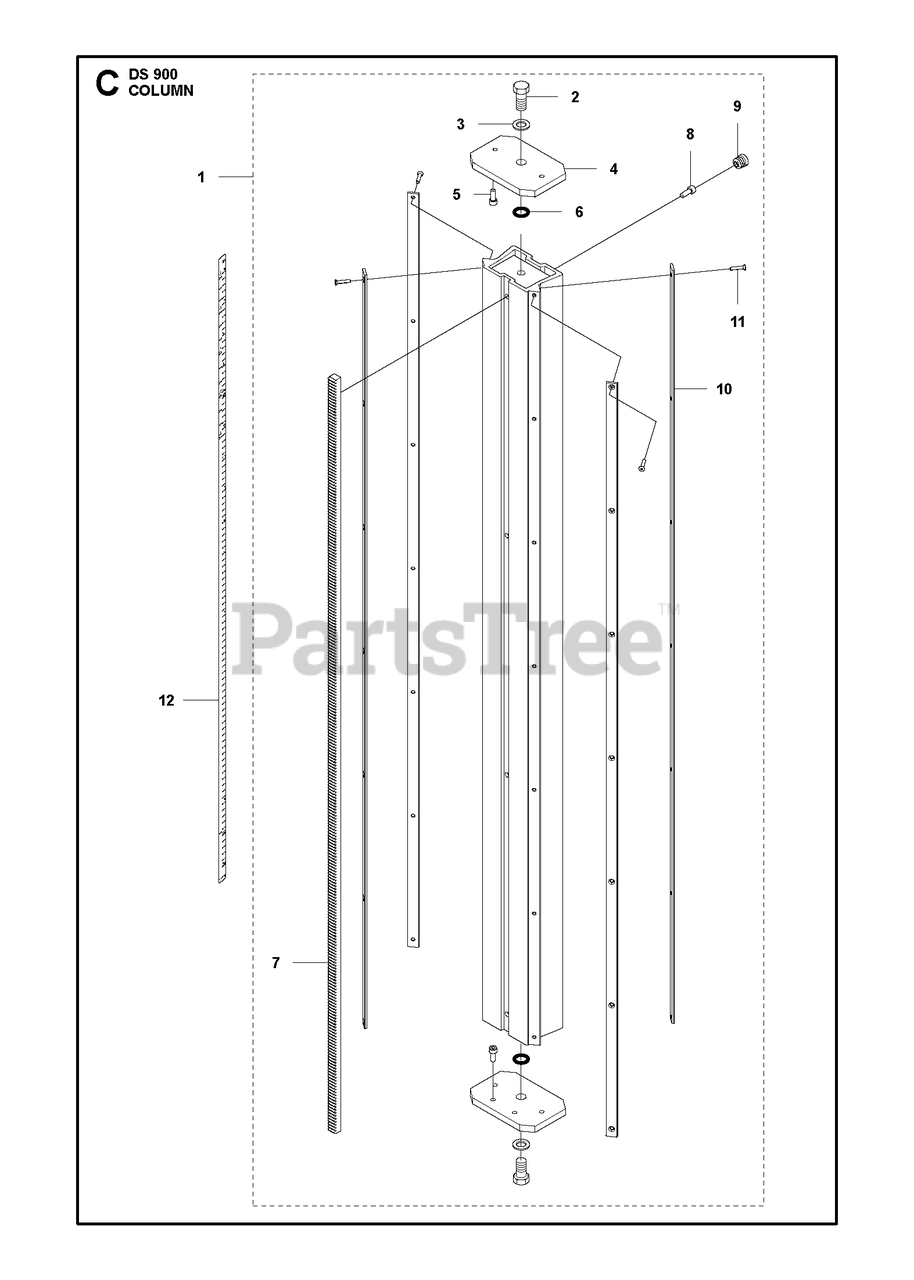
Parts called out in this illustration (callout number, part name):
8	SCREW IHSCM1,2 m
8	SCREW IHSCM2,0 m
8	SCREW IHSCM2,2 m
